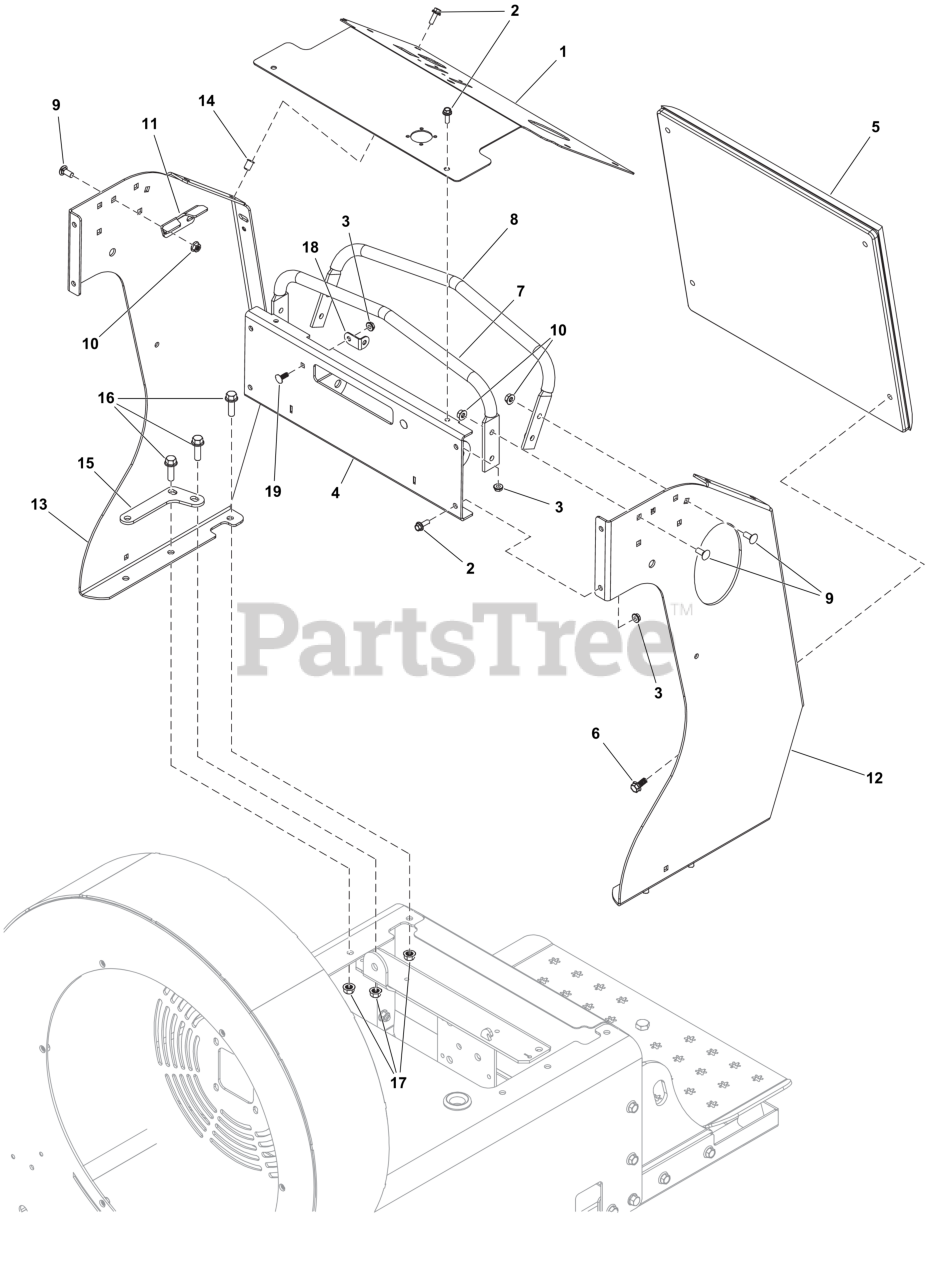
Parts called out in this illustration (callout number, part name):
1	PLATE, Control Panel
4	WELD, DASH FRONT PANEL - ORG
5	PAD, KNEE
6	SCREW, 5/16-18
7	HANDLE, FRONT
8	HANDLE, REAR
9	BOLT, 5/16-18 X 3/4",
10	NUT, 5/16-18 HEX SERR
12	CONTROL TOWER Z3000, LH - TX ORG
13	CONTROL TOWER Z3, RH - ORG
16	BOLT
18	BRACKET, L Headlight Mount
19	BOLT, 1/4-20X.750, SQ
